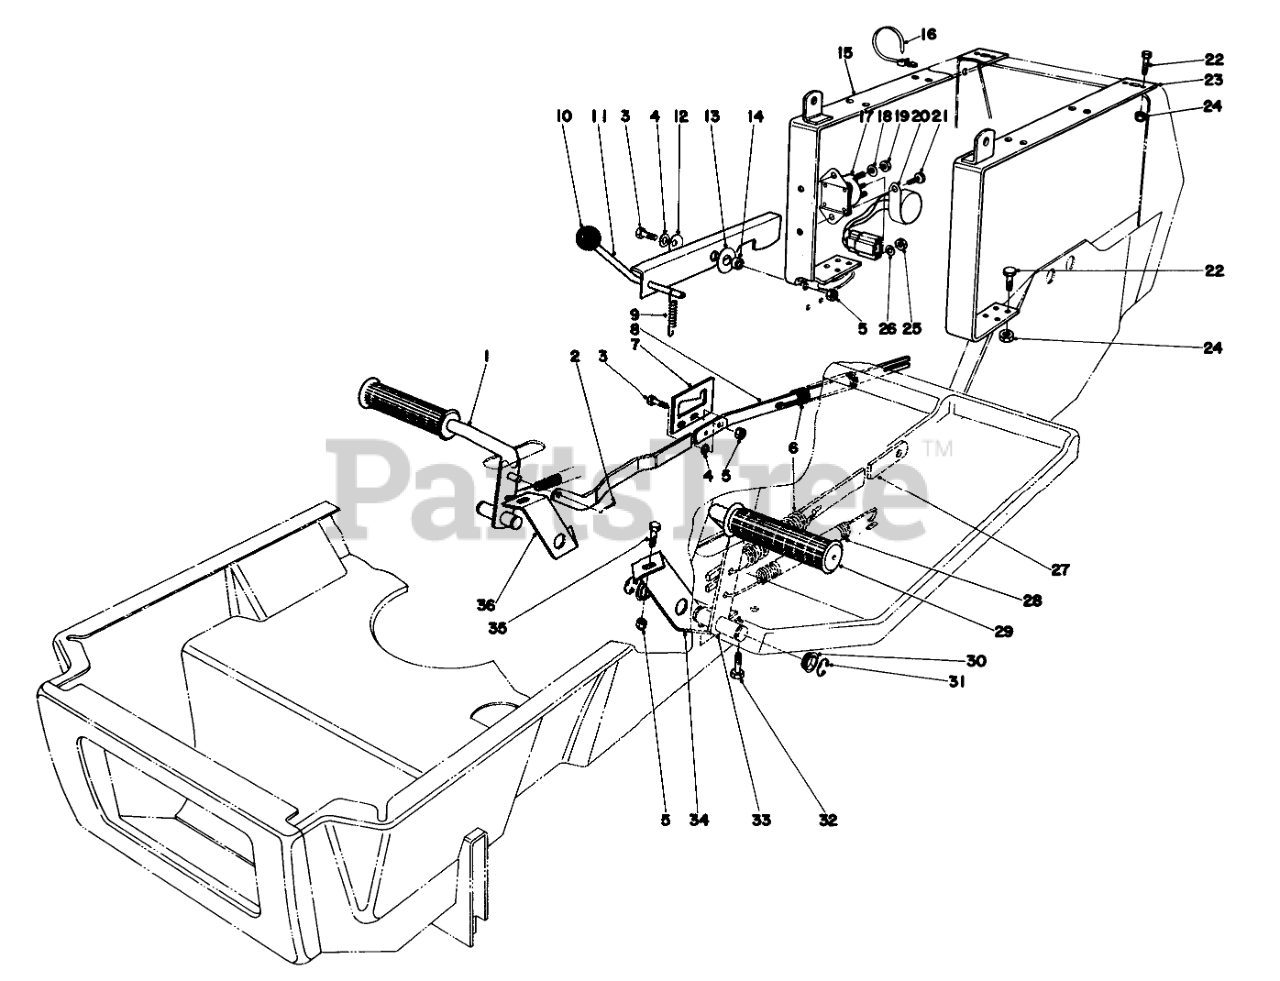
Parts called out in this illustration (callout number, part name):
1	BRAKE PEDAL WA BO
2	PIN-COTTER
3	SCREW-HH
4	WASHER-PLAIN
5	NUT-LOCK, CONE
6	EXT SPRING O
7	LATCH PLT-BRAKE ROD
8	LINK BRAKE ROD WAB
9	CONT ROD SPRING 0
11	PARKING BRAKE WA B
12	Belleville Washer
13	WASHER-PLASTIC
14	SPACER
15	RR BODY STRAP WA B
16	Push Mount Tie
17	SOLENOID
18	WASHER-LOCK
19	NUT-JAM, BRASS
20	Module Interlock
21	SCREW-HWH
22	SCREW-HH
23	LH RR BODY STRAP WA B
24	NUT-LOCK, CONE
25	NUT-HEX
26	WASHER-LOCK
27	CLUTCH ROD LINK B
28	SPRING-EXTENSION
29	FOOT PAD
30	Nyliner
31	E-RING
32	SCREW-HWHTF
33	CLUTCH PEDAL WA BO
34	LH PEDAL SUPT B
35	SCREW-HH
36	RH PEDAL SUPT B
